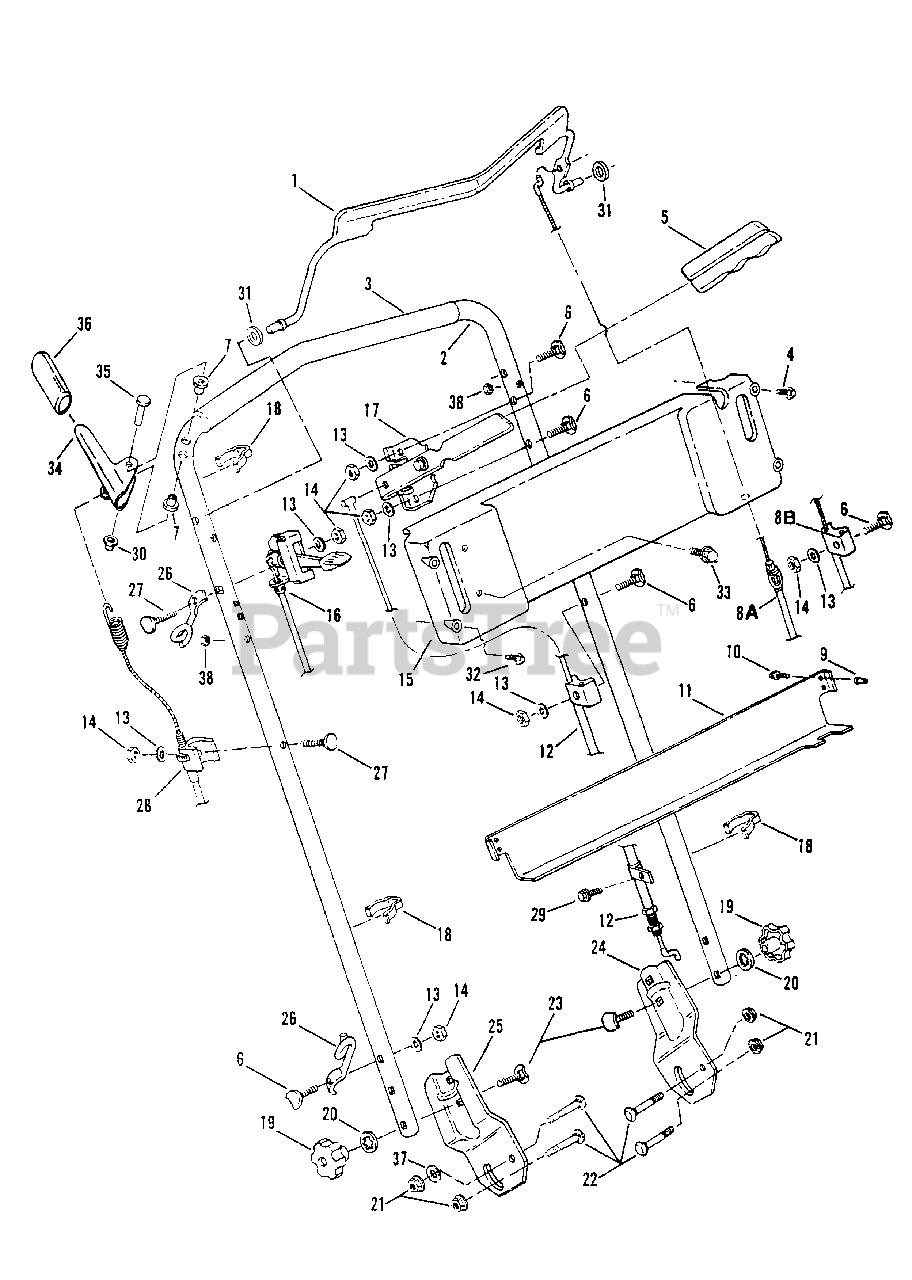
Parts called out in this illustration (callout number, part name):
1	CONTROL, Blade
2	HANDLE, Upper
3	GRIP, Upper handle (Foam)
4	SCREW, #10-24 x 2" Self-Tapping (Gr. 5)
5	GRIP, Speed Selector
6	BOLT, 1/4-20 x 1-1/2" Curved Head Carriage
7	BUSHING
8A	CABLE, Blade Control
8B	CABLE, Blade Control
9	INSERT, Nylon
10	SCREW, #10 x 3/4" Self-Tapping
11	BRACE, Control Panel
12	CABLE, Speed Selector
13	WASHER, 1/4 Internal Tooth Lock
14	NUT, 1/4-20 Hex
15	KIT, Console Panel
16	CONTROL, Throttle (Briggs Engine)
17	ASSEMBLY, Speed Selector Quadrant
18	CLIP, Cable
19	KNOB, 5/16-18 Internal Thread
20	WASHER, 5/16 Internal Tooth Lock
21	NUT, 5/16-18 Hex Flange Lock
22	BOLT, 5/16-18 x 1-1/4" Carriage
23	BOLT, 5/16-18 x 2" Curved Head Carriage
24	BRACKET, Handle (Left Hand)
25	BRACKET, Handle (Right Hand)
26	GUIDE, Rope
27	BOLT, 1/4-20 x 1-7/8" Curved Head Carriage
28	ASSEMBLY, Clutch Cable
29	SCREW, 1/4-20 x 3/8" Self-Tapping
30	NUT, 1/4" Push
31	WASHER, 5/16 Flat
32	SCREW, #10-24 x 1-1/2" Self-Tapping (Gr. 5)
33	SCREW, #10-24 x 1/2" Hex Washer Self-Tap (Torx)
34	LEVER, Wheel Drive
35	PIN, 1/4 x 1-1/2" Clevis
36	GRIP, Wheel Drive Lever
37	WASHER, 5/16 Flat
38	NUT, #10-24 Hex Center Lock
